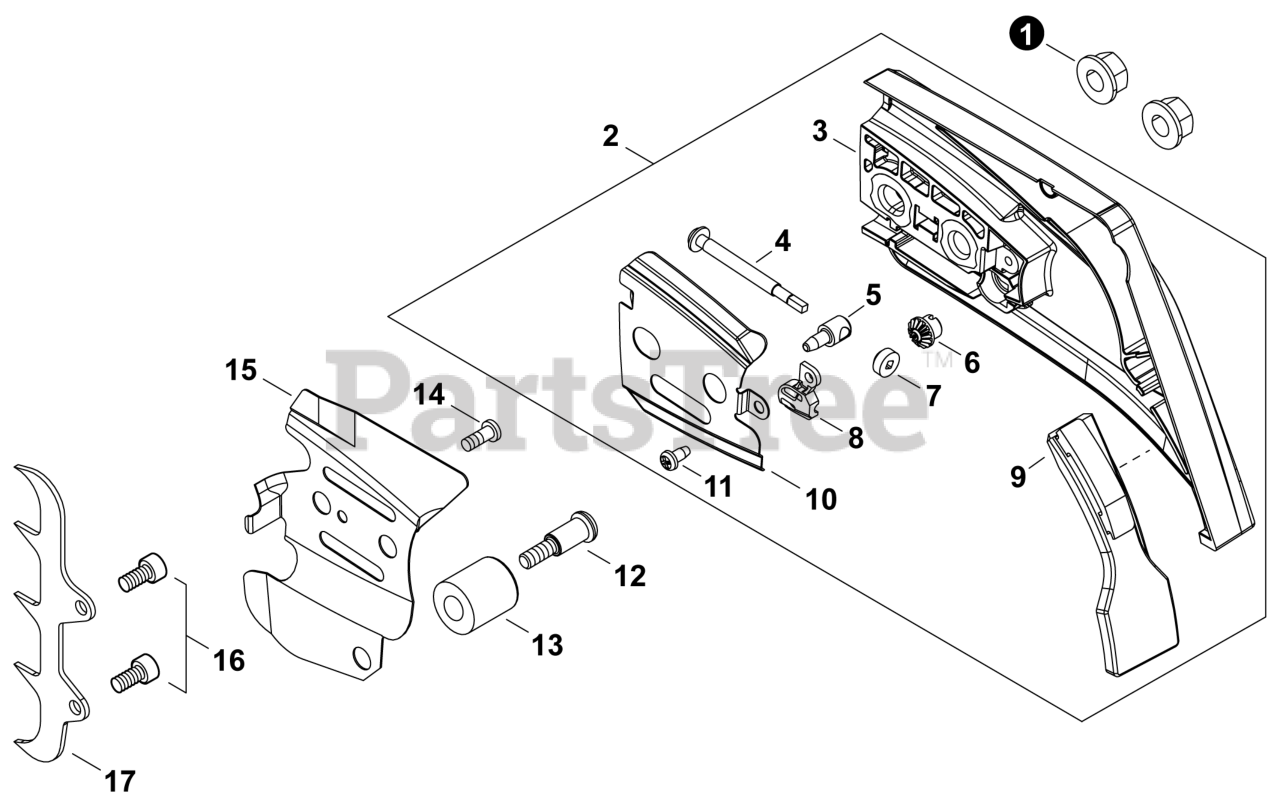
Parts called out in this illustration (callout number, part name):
1	NUT, FLANGE M8x1.25
2	SPROCKET GUARD ASSY
3	GUARD, SPROCKET
4	SCREW, CHAIN TENSION
5	TENSIONER, CHAIN
6	GEAR, BEVEL
7	GEAR, BEVEL
8	COLLAR 8
9	PROTECTOR
10	PLATE, GUIDE - OUTER
11	SCREW 4x8
13	CATCHER, CHAIN
14	SCREW M4x7
15	PLATE, GUIDE - INNER
16	BOLT 5x12
17	SPIKE, BUMPER
